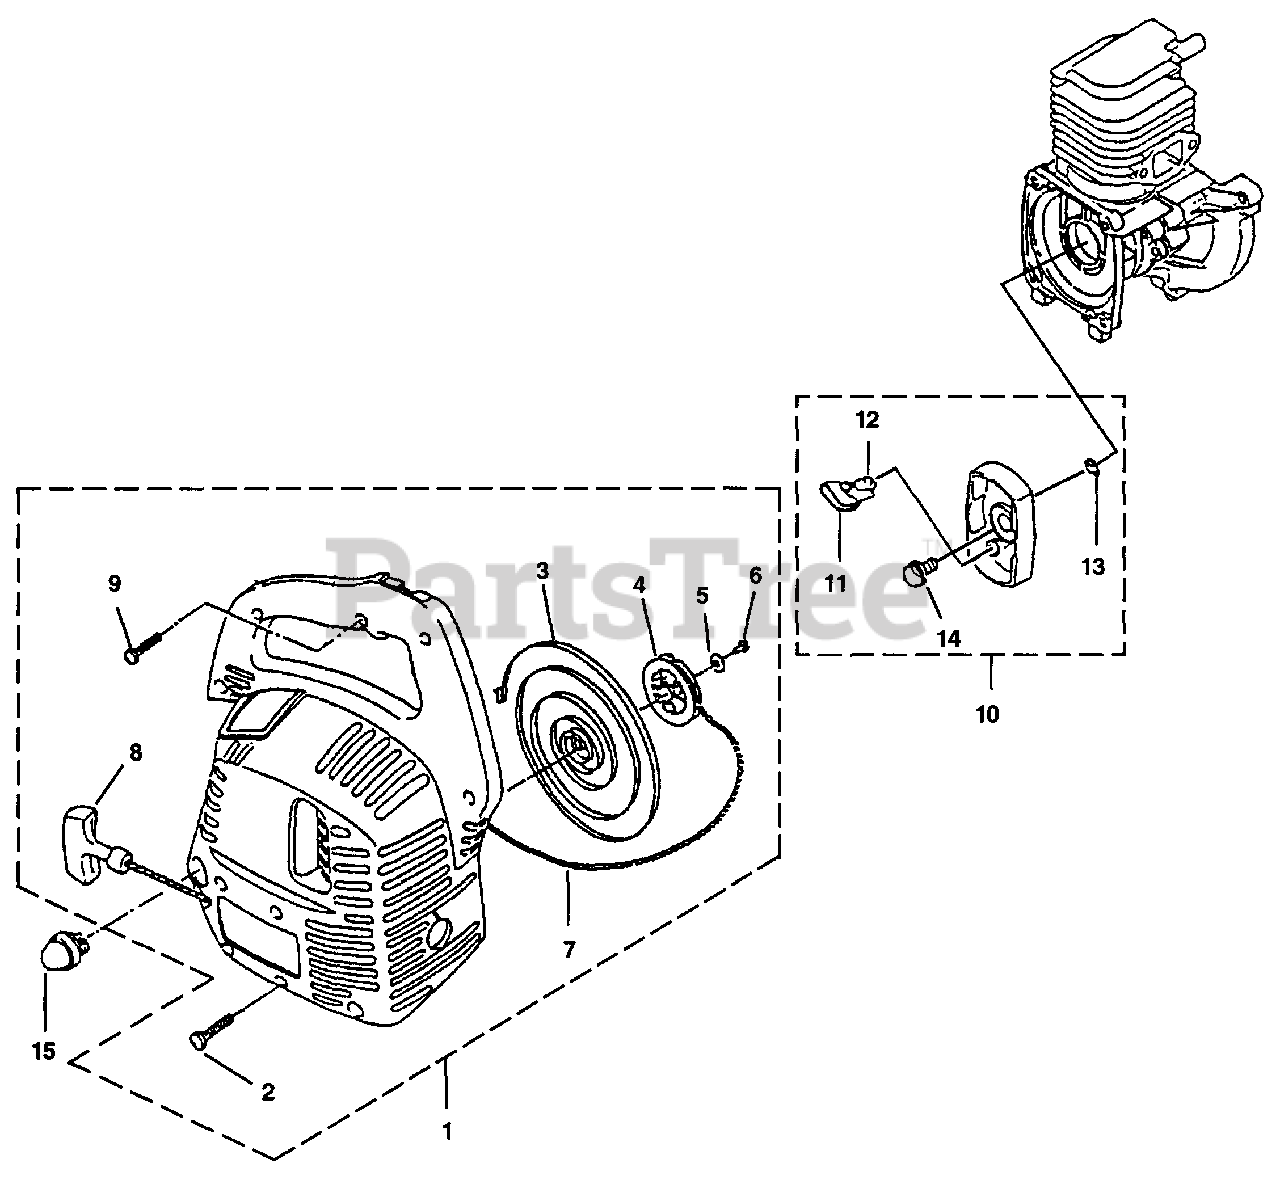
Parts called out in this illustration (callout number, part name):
1	STARTER COMPLETE
2	SCREW-Socket Hd (M5 x 18 W SW)
6	SCREW (M6 x 14)
7	ROPE-Starter
9	SCREW-Tapping (M5 x 20)
10	STARTER CUP ASSEMBLY
12	SPRING-Return
14	BOLT ASSEMBLY (M6 x 14)
15	PRIMER BULB
